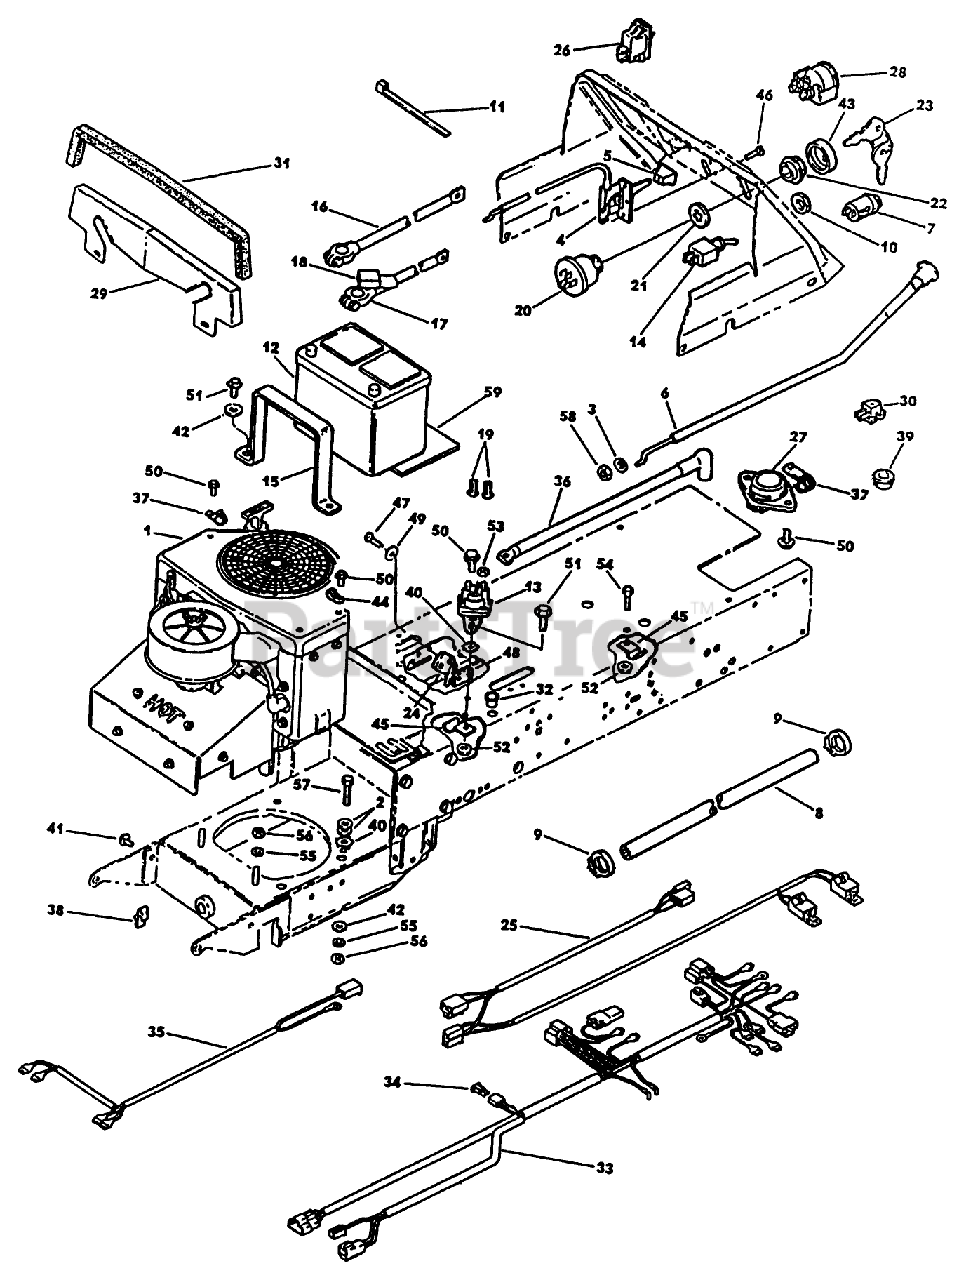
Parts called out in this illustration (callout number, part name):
1	Engine-Kohler 16 H.P.
3	WASHER
4	THROTTLE CONTROL
5	THROTTLE KNOB
7	LIGHT-PTO INDICTOR
13	SOLENOID
14	SWITCH-PTO W/SAFTY
15	STRAP & DECAL AY.
22	NUT
23	KEY
24	SWITCH-SEALED
26	SWITCH ASSEMBLY
27	SWITCH,SEAT
29	DAM - AIR
30	SWITCH
38	CLIP
43	BEZEL
53	NUT-HEX
54	SCREW-HH
56	NUT SS
58	NUT-HEX
